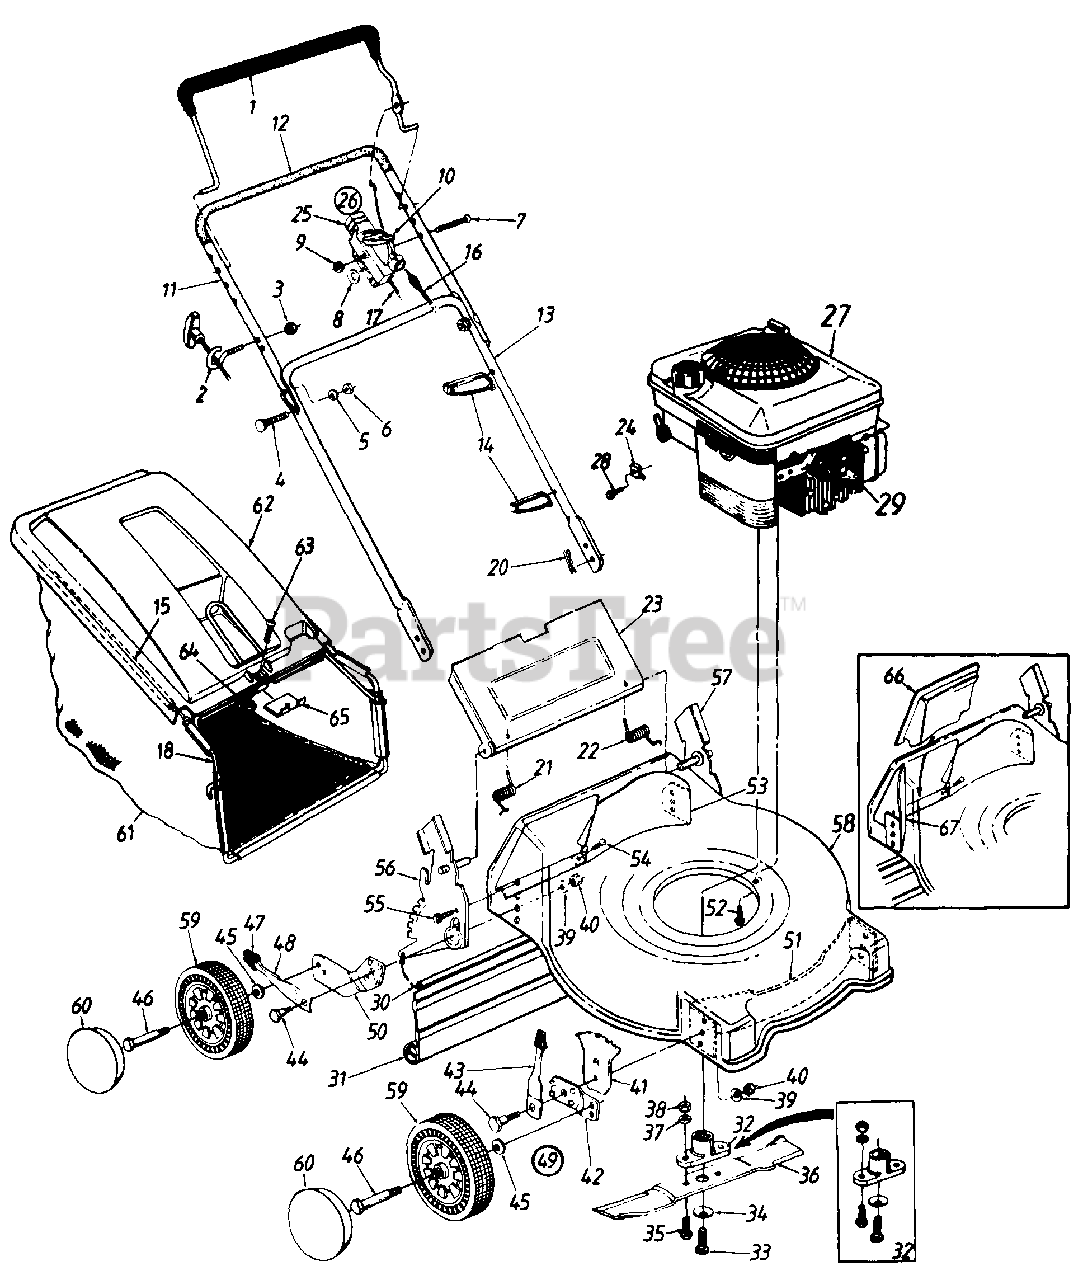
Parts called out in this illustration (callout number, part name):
1	Control Handle Ass'y.
2	Rope Guide Bolt
3	Hex L-Nut 1/4-20 Thd.
4	Curved Carr. Bolt 5/16-18 x 1.38" Lg.
5	L-Wash. 5/16" I.D.
6	Hex Nut 5/16-18 Thd.
7	Oval C-Sunk Mach. Scr.
8	Spr. Wash. .66" I.D.
9	Hex L-Nut 1/4-20 Thd.
10	Throttle Lever
13	Lower Handle
14	Cable Tie
16	Control Cable - 36"
17	Throttle Control Wire - 55"
21	Door Spring - R.H.
22	Door Spring - L.H.
25	Throttle Body
26	Throttle Box Comp.
27	Engine
28	Hex Wash. Hd. Scr. #10-32 x .62" Lg.
29	Spark Plug Boot
30	Wire Rod
31	Rear Flap
32	Blade Adapter Kit
33	Hex Bolt 7/16-20 x 1.5" Lg.
34	Bell-Wash. .46" I.D.
35	Hex Bolt 3/8-24 x 1" Lg.
36	21" Mulching Blade
37	L-Wash. 3/8" I.D.
38	Hex Nut 3/8-24 Thd.
39	Bell-Wash. .39" I.D. x 1.38"
40	Hex Nut 3/8-16 Thd.
41	Height Adj. Plate
43	Spring Lever Ass'y. w/Knob
44	Shld. Bolt .5" Dia. x .357"
45	Bell-Wash. .38" I.D. x .88" O.D.
47	Spring Lever Knob
49	Height Adj. Ass'y. Comp.- R.H.
54	Torx Mach. AB-Tap Scr. 1/4 x .62" Lg.
55	Hex L-Wash. Hd. AB-Tap Scr. 1/4 x .62" Lg.
56	Handle Brkt. Ass'y. - R.H.
57	Handle Brkt. Ass'y. - L.H.
60	Hub Cap
61	Grass Bag
62	Hard Top Cover
63	Pan Hd. Mach. Scr. 1/4-20 x .5" Lg.
64	Hex Nylon L-Nut 1/4-20 Thd.
